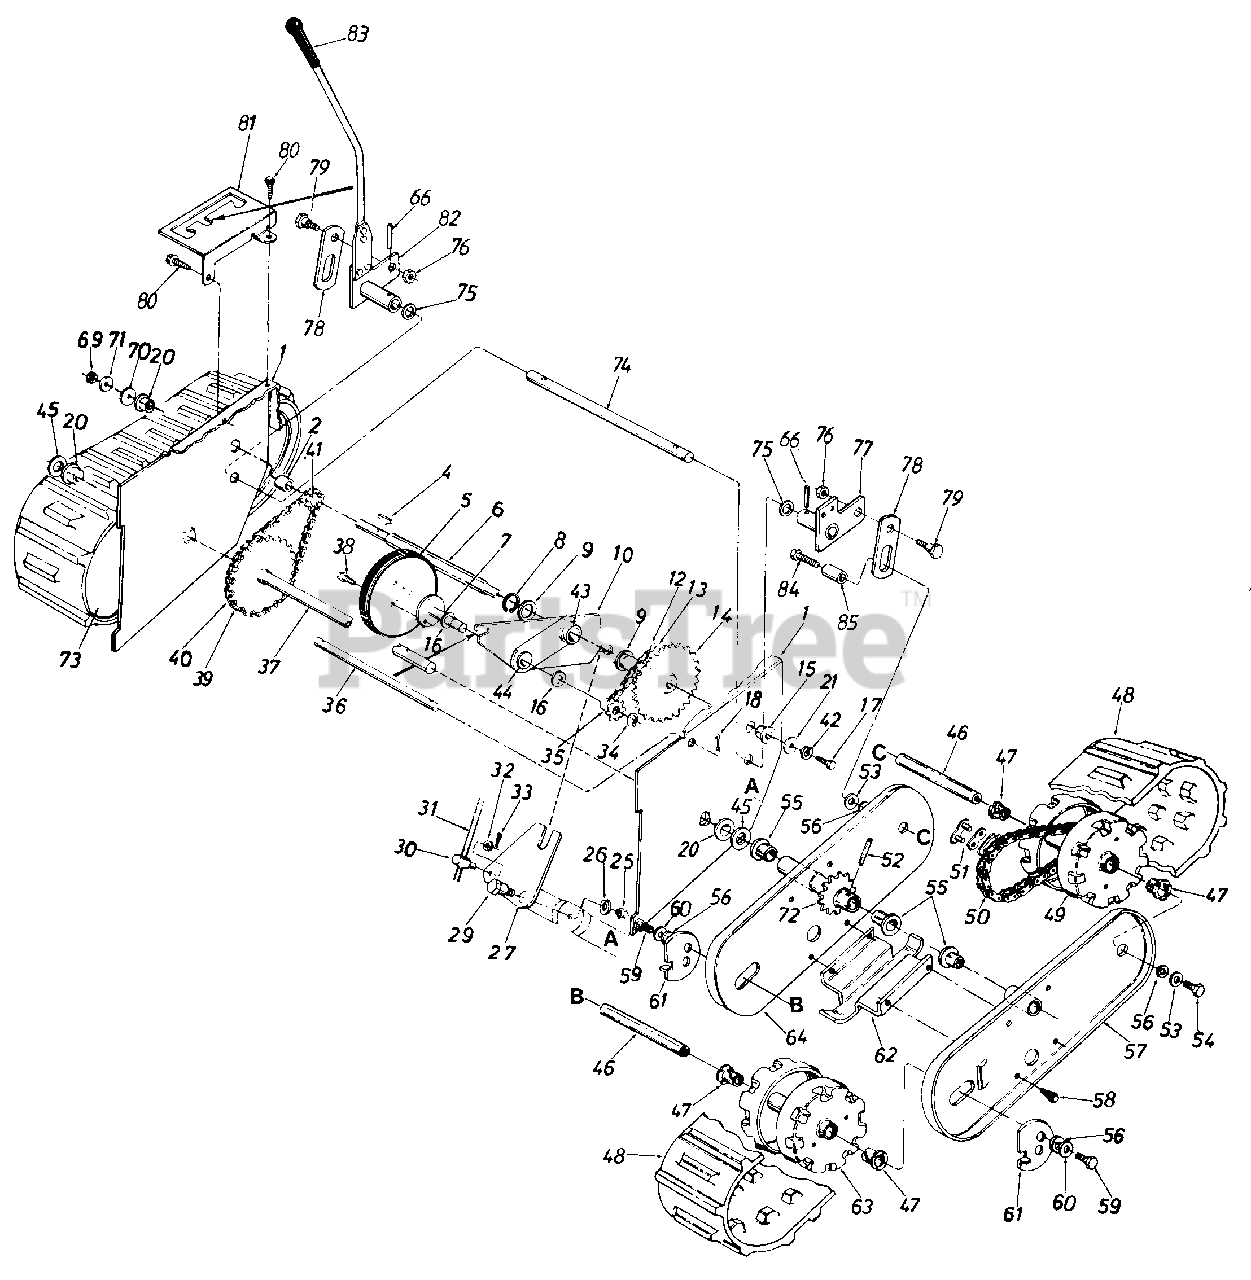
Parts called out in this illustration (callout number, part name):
1	Frame Ass'y.
2	Spacer 50n l.D. x .75" O.D. x.78" Lg.
4	#4 Hi-Pro Key 3/32 x 5/8" Dia.
5	Friction Wheel Ass'y.
7	Friction Wheel Mounting Plate Ass'y.
8	Snap Ring 1.00" Dia. Shaft
9	Fl-Wash. 1.00" x 1.63" O.D. x .03
10	Sliding Bracket Ass'y.
12	#41 Chain 1/2" Pitch x 35 Links
13	Master Link for #41 Chain
14	32 Teeth Sprocket Ass'y.
15	Hex Flange Brg. .630" I.D.
16	Fl-Wash. .62" I.D. x 1.00" O.D. x .06
17	Hex Lock Bolt 5/16-18 x .62" Lg.
18	Cotter Pin 3/32" Dia. x .75" Lg.
20	Flange Brg. w/Flats .756" I.D.
21	Fl-Wash. .34" I.D. x 1.12" O.D. x . 1 25
25	Hex Jam Nut 3/8-16 Thd.
26	L-Wash. 3/8" I.D.
27	Shifting Linkage Bracket
29	Shld. Bolt .625" Dia. x .170" Lg.
30	Adjustment Ferrule
31	Shifting Rod 5/16" Dia. x 32.50" Lg.
32	Fl-Wash. .34" I.D. x .64" O.D. x .06
33	Cotter Pin 3/32" Dia. x .75" Lg.
34	Snap Ring .562" Dia. Shaft
35	Sprocket 7 Teeth x .50" Pitch
36	Shaft .50" Dia. x 9.50" Lg.
37	32 Teeth Wheel Shaft Ass'y.
38	Hex Wash. Hd. Self-Tap Scr. 5/16-24 x .50" Lg.
39	#420 Chain 1/2" Pitch x 39 Links
40	Master Link for #420 Chain
41	8 Teeth Center Sprocket
42	L-Wash. 5/16" I.D.
43	Plastic Bearing
44	Bronze Bearing
45	Fl-Wash. .76" I.D. x 1.49 O.D.
46	Wheel Shaft 5/8 x 4.25" Lg.
47	Flange Brg. .632" I.D.
48	Snow Track 5" x 48"
49	Drive Wheel Ass'y.
50	Chain #420 x 50 Pitch x 37 Link
51	Master Link #420
52	Spring Pin Spir. 1/4n Dia. x 1.50" Lg.
53	Bell-Wash. .345" I.D. x .88" O.D.
54	Hex Bolt 5/16-24 x .62" Lg.
55	Flange Brg. .757" I.D.
56	Fl-Wash. .510" I.D. x 1.0" O.D.
57	Outer Plate Ass'y.-L.H.
58	Hex Wash. S-Tap Scr. 1/4-20 0 x.50" Lg.
59	Hex Bolt 5/16-24 x .62" Lg.
60	Bell-Wash. .345" I.D. x .88" O.D.
61	Track Adjuster
66	Spring Pin l/4n x 1.25n Lg.
69	Hex Ins. L-Nut 1/2-20 Thd.
70	Fl-Wash. .53 I.D. x 1.25 O.D. x .1
71	Bell-Wash. .50 I.D. x 1.0 O.D. x .075
72	17T Sprocket Hub Ass'y.
73	Inner Plate Ass'y.-R.H.
74	Track Lock Axle
75	Fl-Wash. 5/8 I.D. x 1" O.D.
76	Hex L-Nut 3/8-16 Thd.
77	Pivot Arm Ass'y.-L.H.
78	Slotted Link
79	Shld. Bolt .625" Dia. x .217
80	Hex Wash. AB-Tap Scr. 5/16 x 75n Lg.
81	Position Selector Plate
82	Track Lock Handle Ass'y.
84	Hex Bolt 5/16-24 x 1.25n Lg. Gr. 5
85	Spacer.325" I.D.
